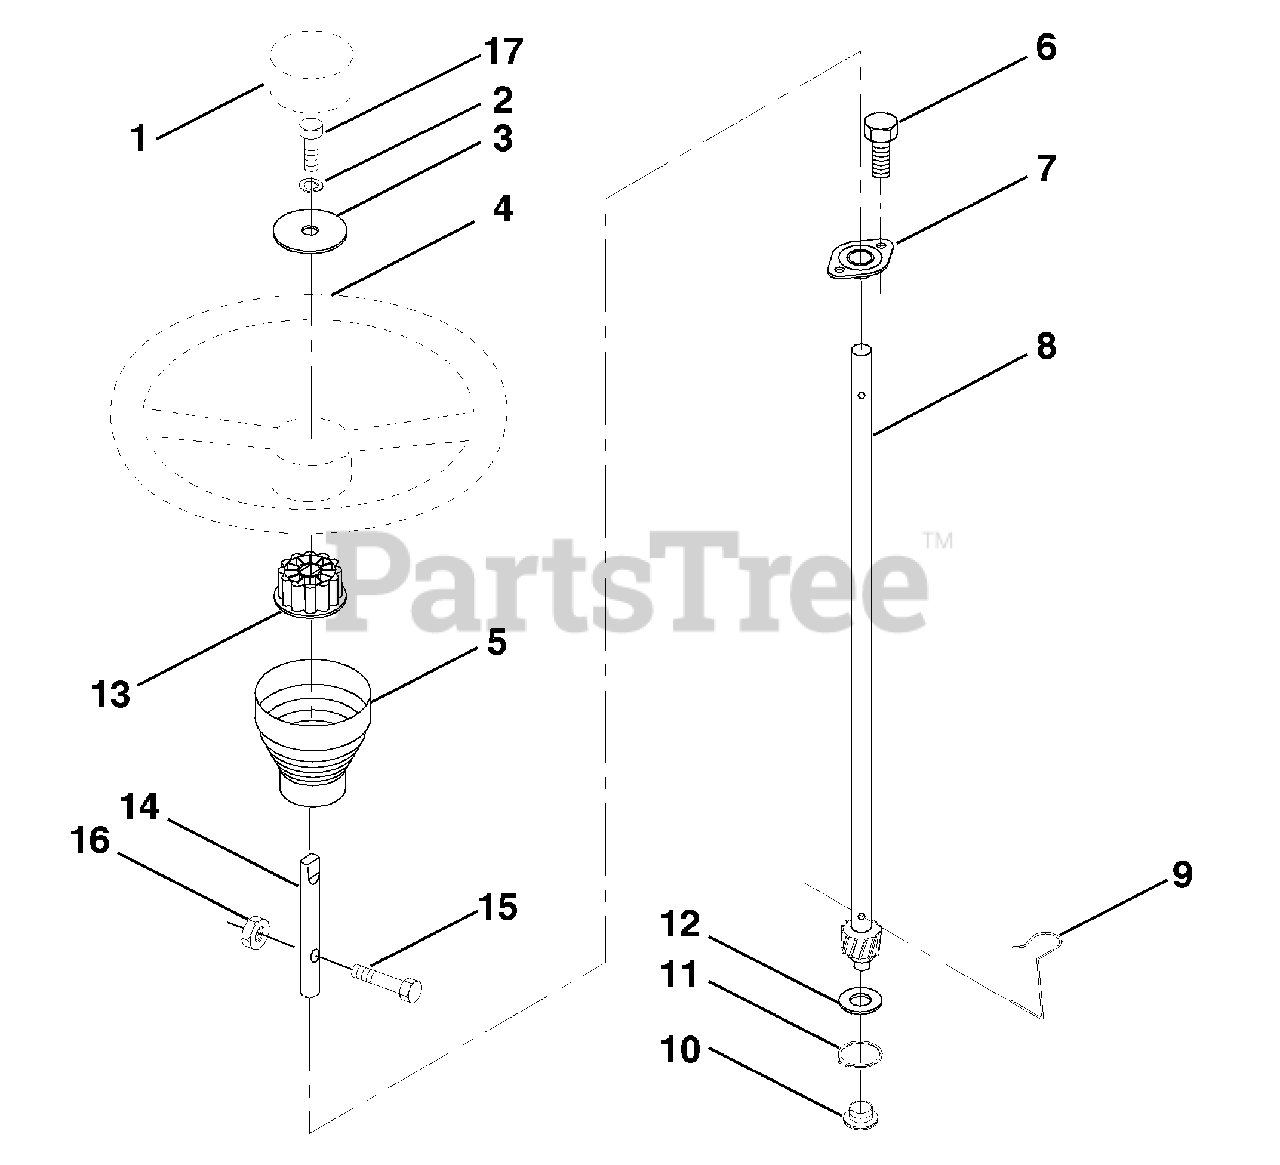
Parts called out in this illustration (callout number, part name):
1	Insert, Wheel, Steering
2	Washer, Lock hvy HLCL SPR 3/8
3	Washer 12/32 x 2-3/8 x 8 Ga.
4	Wheel, Steering
5	Sleeve, Steering
6	Screw, TT #10-32.5.3/8 flange
7	Bushing, Steering
8	Shaft, Steering
9	Clip, Steering
10	Bushing, Lower, Steering
11	Ring, Retaining
12	Washer 21/32 x 1 x 16 Ga.
13	Adaptor, Wheel, Steering
14	Extension shaft steering
15	Bolt Fin Hex 5/16-18 UNC x 1-1/4
16	Nut Lock Hex W/Ins. 5/16-18 UNC
17	Bolt fin Hex 3/8-16 UNC x 1. Gr. 5
